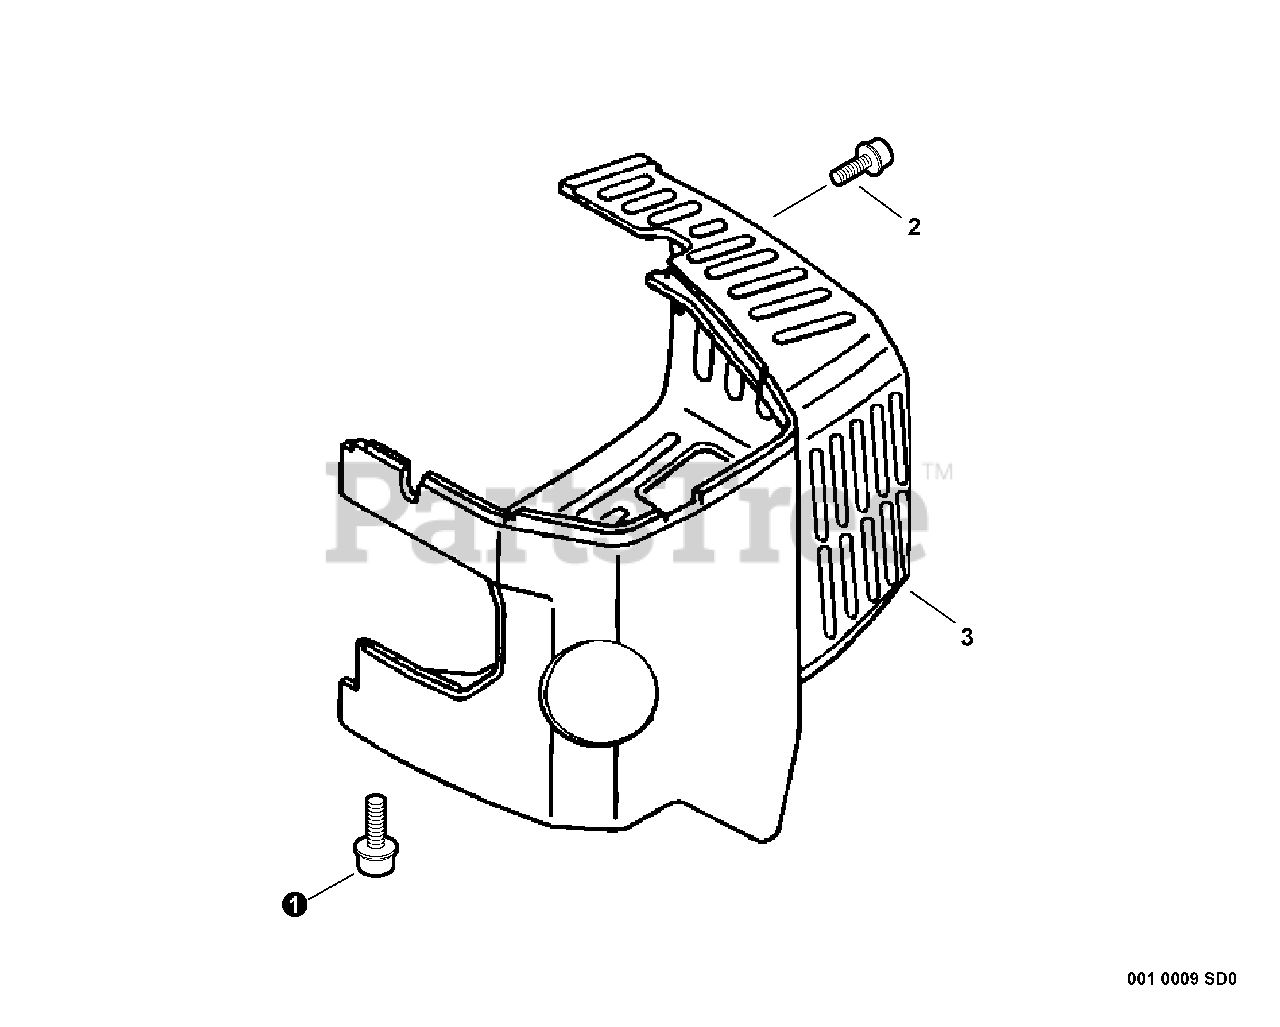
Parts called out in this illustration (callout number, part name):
1	SCREW - 4X20
2	SCREW - 4X8
3	COVER, ENGINE
